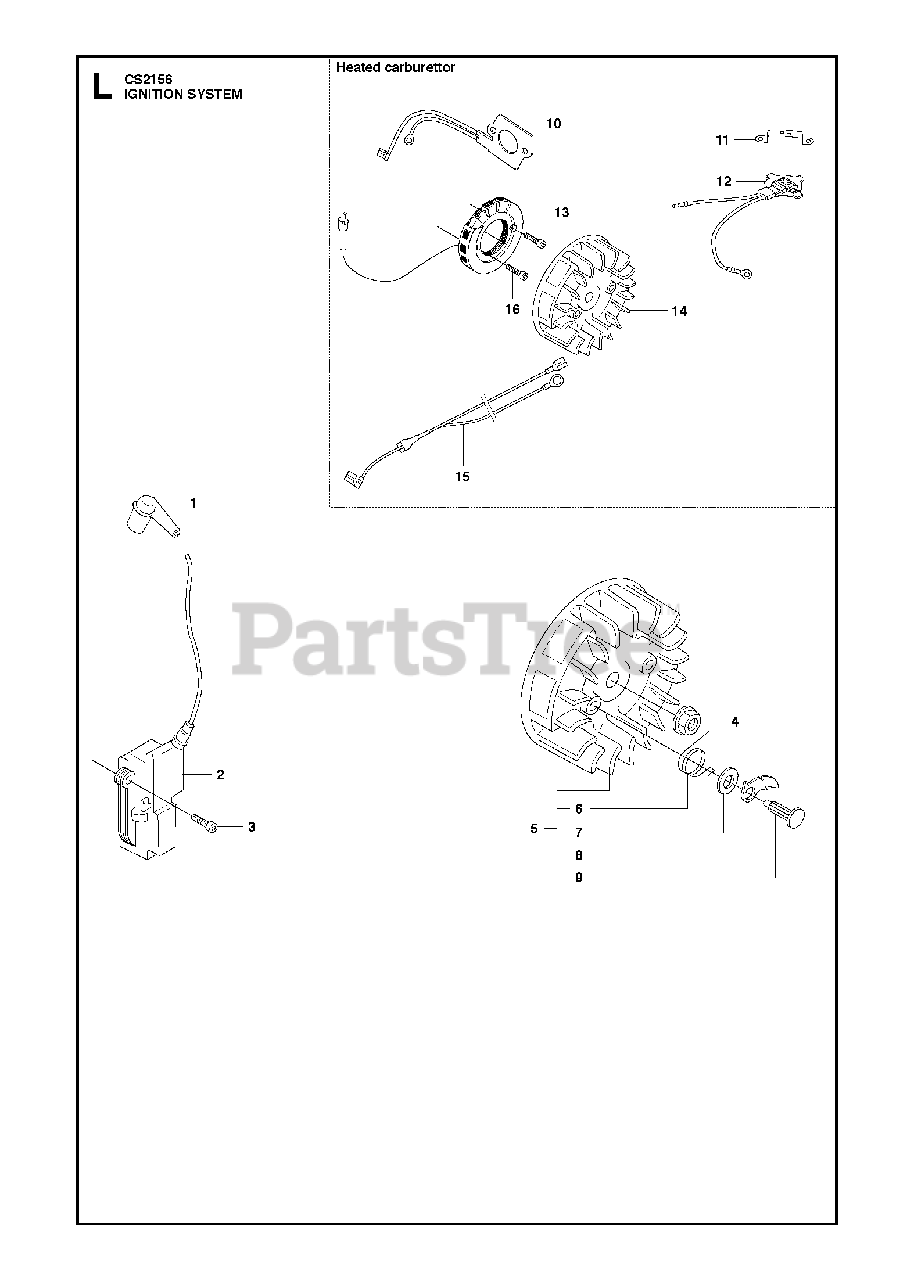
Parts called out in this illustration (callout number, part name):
1	SPARK PLUG CONN. KIT
2	IGNITION MODULE
4	NUT W/ WASHER
6	SPRING
7	WASHER
8	PAWL
9	PIN, STARTER CATCH
10	HEATING PLATE
11	RETAINER
12	THERMOSTAT ASSY
13	GENERATOR STATOR
14	FLYWHEEL
15	WIRING ASSY
16	SCREW
